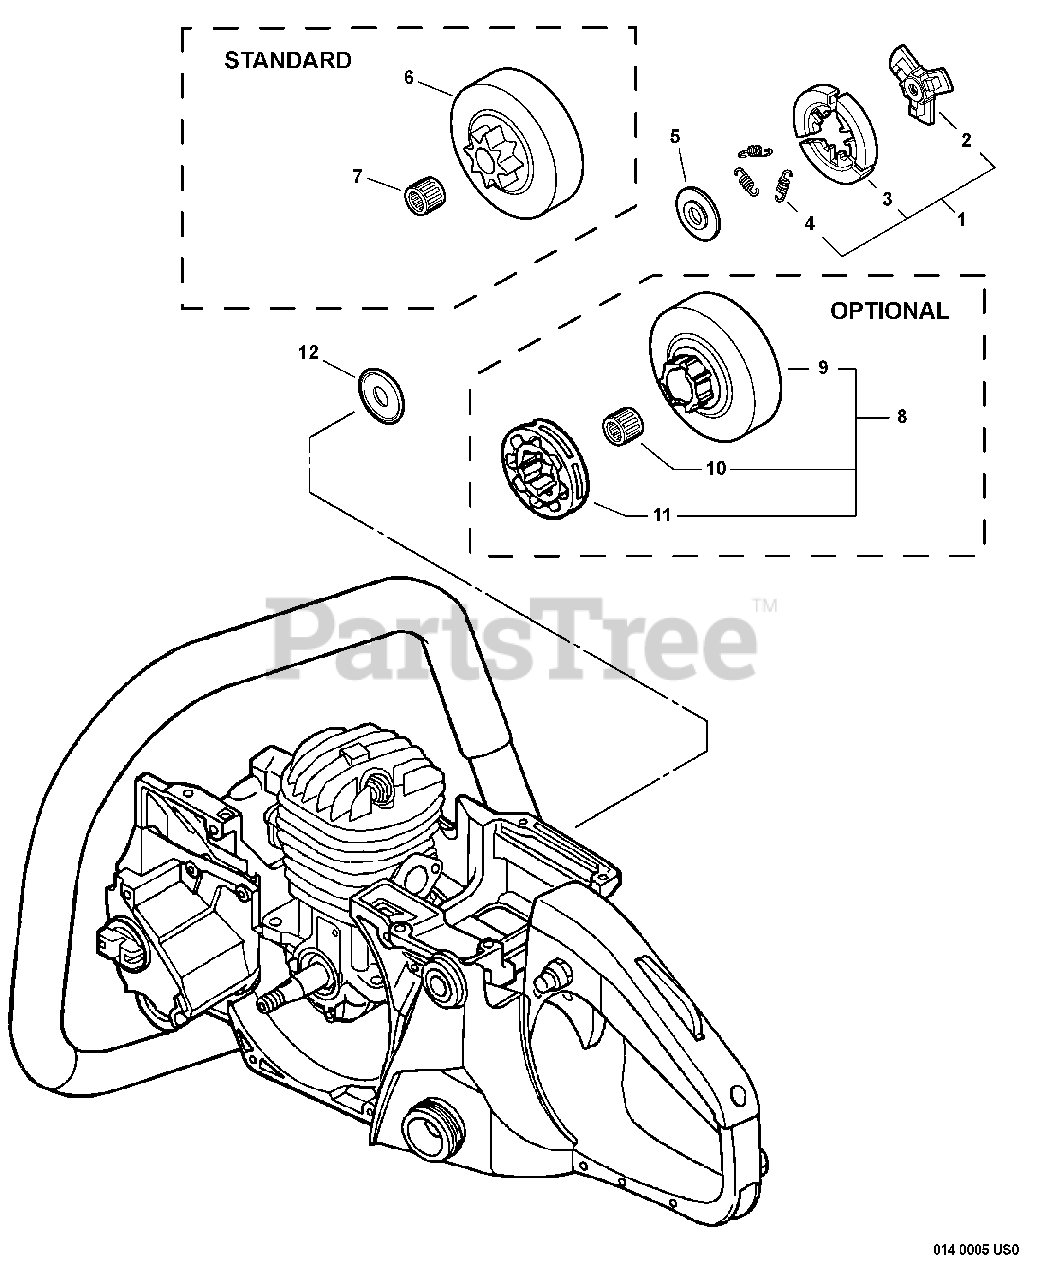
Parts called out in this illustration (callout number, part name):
1	CLUTCH ASSY
2	HUB, CLUTCH
3	SHOE SET, CLUTCH (3PCS)
4	SPRING, TENSION
5	PLATE, CLUTCH
6	DRUM, CLUTCH
7	BEARING, NEEDLE
8	RIM SPROCKET KIT
9	DRUM, CLUTCH
10	BEARING, NEEDLE
11	SPROCKET, 0.325 RIM
12	PLATE, CLUTCH
